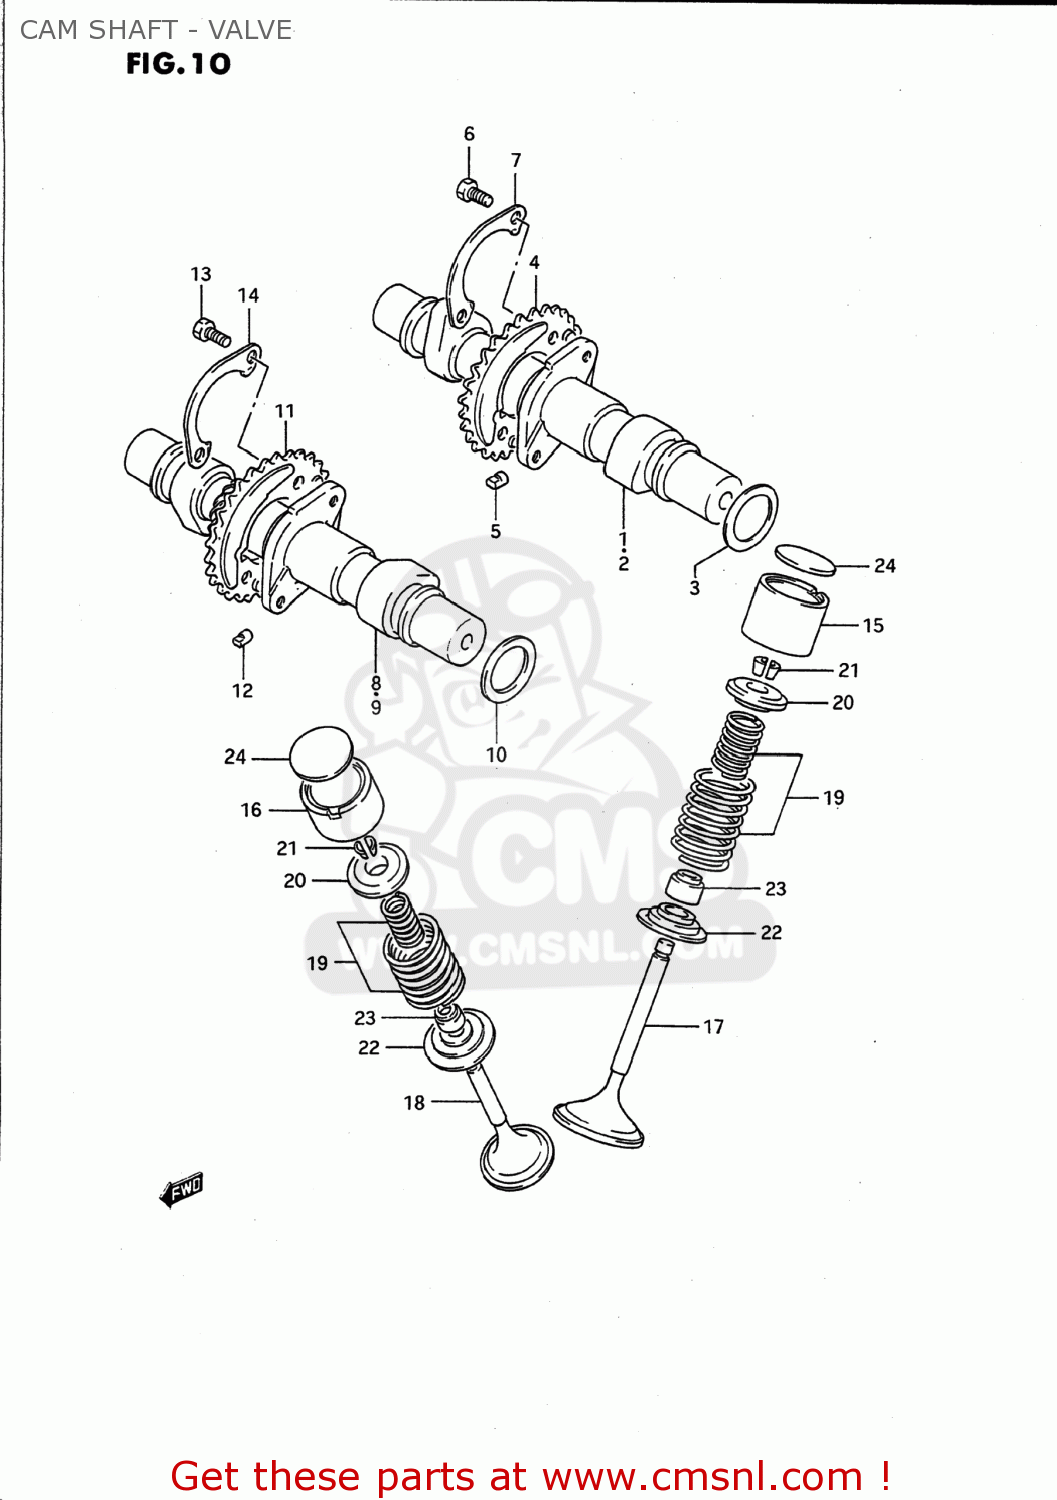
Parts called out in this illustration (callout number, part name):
1	CAMSHAFT
2	CAMSHAFT SET,INTAKE
3	WASHER,THRUST
4	SPROCKET,CAMSHAFT INTAKE
5	PIN,SPROCKET
6	BOLT(6X12.5)
7	WASHER,CAM CHAIN SPROCKET
8	CAMSHAFT,EXHAUST
9	CAMSHAFT SET,EXHAUST
10	WASHER,THRUST
11	SPROCKET,EXHAUST CAM(NT:30)
12	PIN,SPROCKET
13	BOLT(6X12.5)
14	WASHER,CAM CHAIN SPROCKET
15	TAPPET
16	TAPPET
17	VALVE,INTAKE
18	VALVE,EXHAUST
19	SPRING SET,VALVE
20	RETAINER,VALVE SPRING
21	COTTER VALVE
22	SEAT,VALVE SPRING
23	SEAL,OIL(7X14.4X9)
24	SHIM,TAPPET(T:2.15)
25	SHIM SET,TAPPET
26	CASE,SHIM
